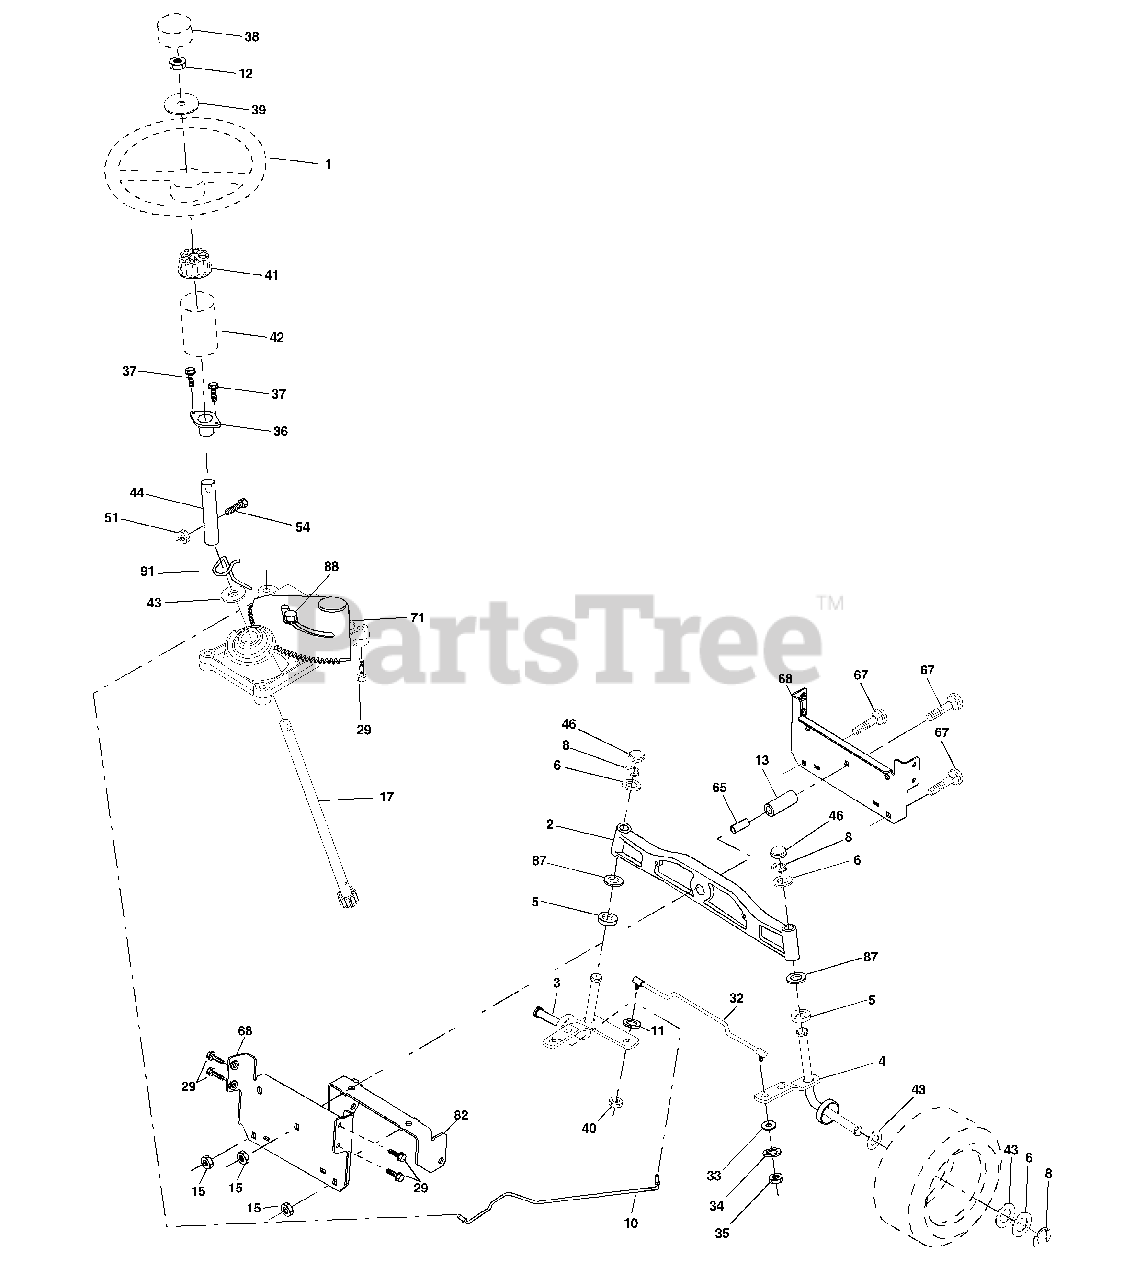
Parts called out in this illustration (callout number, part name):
1	Wheel Steering
2	Axle Asm Cast Iron LT
3	Spindle Asm LH
4	Spindle Asm RH
5	Bearing Race Thrust Harden
6	Washer 25/32 X 1-5/8 X 16 Ga
8	Ring Klip #t5304-75
10	Link Drag
11	Washer Lock Hvy Hlcl Spr 3/8
12	Nut Hex Jam Toplock 1/2-20 UNF
13	Spacer Brg. Axle Front
15	Nut Hex Flange Lock
17	Shaft Asm. Steering
29	Screw 3/8-16x.75
32	Rod Tie
33	Washer 11/32 x 3/4 x 16 Ga.
34	Washer Lock Hvy Hlcl Spr 5/16
35	Crownlock Nut 5/16-24
36	Bushing Strg
37	Screw
38	Insert Cap Strg Wh Au
39	Washer 9/16 ID x 1 1/2 OD.11 Ga
40	Lock nut
41	Adaptor Wheel Strg
42	Boot Steering Dash
43	Washer 25/32 X 1 1/4 X 16 Ga
44	Extension Steering Shaft LR/LT
46	Cap Spindle Fr Top Blk
51	Nut Crownlock 1/4-28
54	Bolt Hex 1/4-28 UNF x 1-1/4 Ga 8
65	Brace Axle
67	Bolt Rdhd Sq 3/8-16 Unc x 2-1/4
68	Axle, Brace
71	Steering Asm.
82	Bracket Susp. Chassis Front
87	Washer Flat .781 x 1-1/2 x .14
88	Bolt Shoulder 7/16-20 Unc
91	Clip Steering
